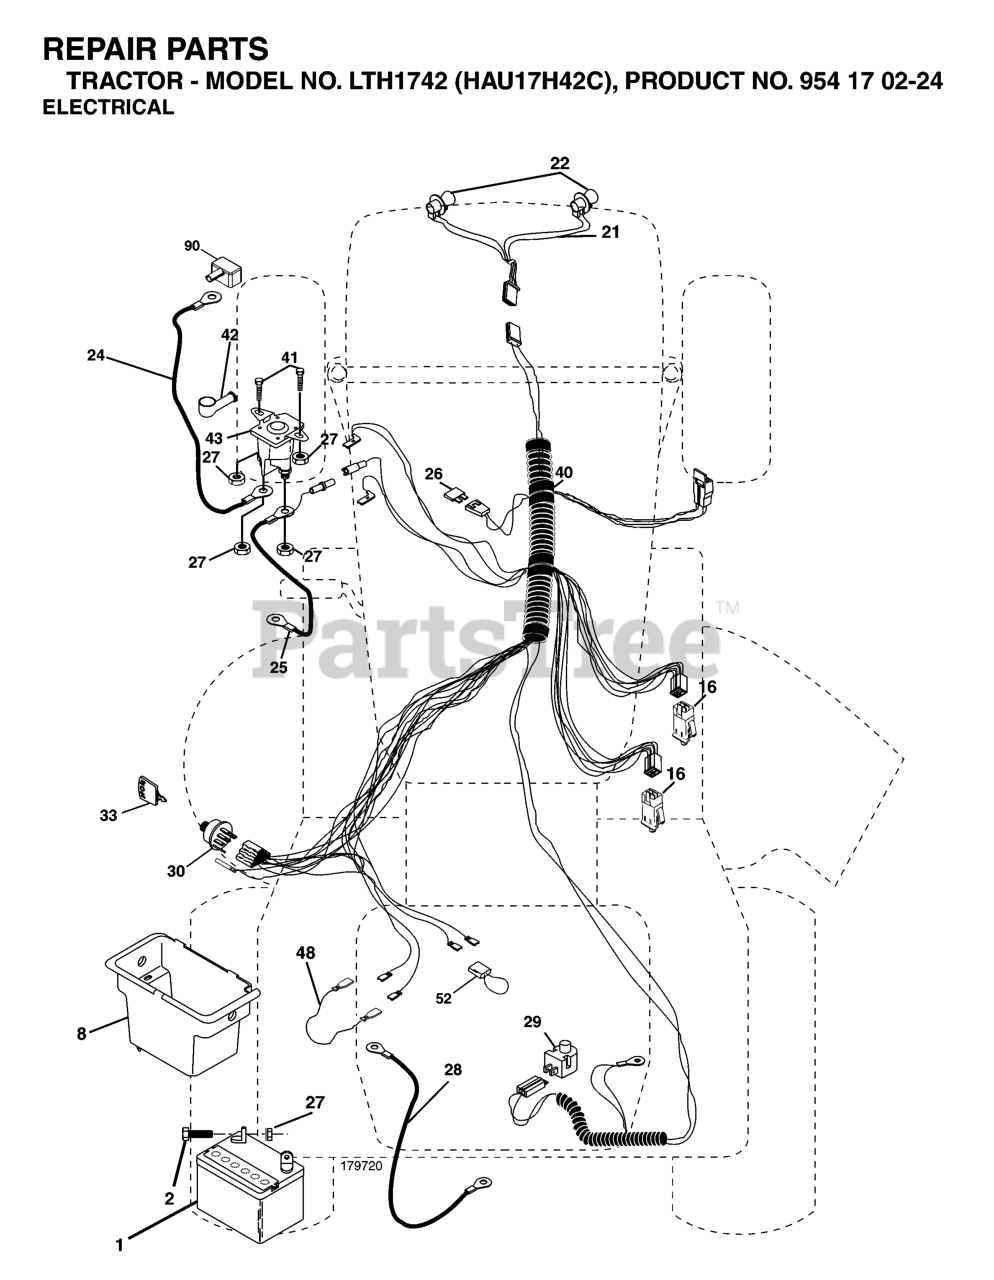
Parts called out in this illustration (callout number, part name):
1	BATTERY 12V .35 AMP
2	BOLT.HEX.1/4.X.3/4.DICHROMATE
8	BOX.BATTERY.FENDER
16	SWITCH INTERLOOK PUSH-IN
21	HARNESS.W/LIGHT SOCKET
24	BATTERY CABLE GT
25	CABLE BATTERY
26	FUSE 20AMP
27	NUT
28	CABLE T
29	RP.SWITCH.PLUNGER.NC.GRAY
30	IGNITION SWITCH
33	KEY MLD GEN DELTA
40	HARNESS.IGNITION
41	BOLT
42	TERMINAL COVER
43	SOLENOID
48	ADAPTER.AMMETER
52	WIRE PROTECTION LOOP
90	COVER TERMINAL
